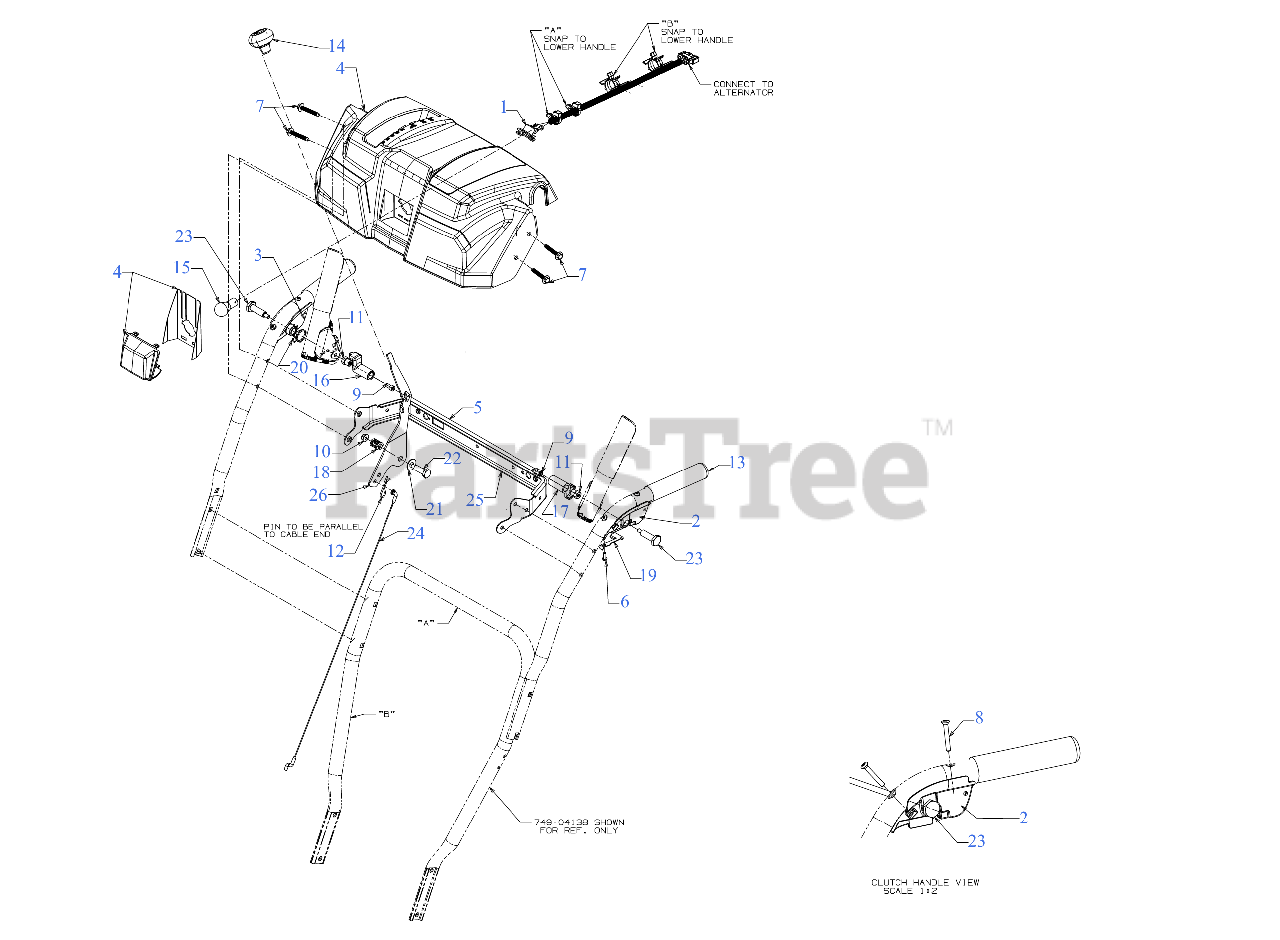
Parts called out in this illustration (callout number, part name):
1	LIGHT HARNESS
2	CLUTCH LOCK HANDLE ASSEMBLY (LH)
3	CLUTCH LOCK HANDLE ASSEMBLY (RH)
4	HANDLE PANEL(W/LIGHT)
6	SCREW #8-16 x .50
7	SCREW 1/4-20 x 1.625
8	SCREW #10-24 x 1.375
9	SCREW 1/4-20 x .50
10	FLANGE LOCK NUT
11	HEX NUT W/PATCH
12	INTERNAL COTTER PIN
14	SHIFT KNOB
15	LAMP-12 VOLT
17	CLUTCH LOCK CAM
18	COMPRESSION SPRING
19	CLUTCH SPRING
20	TORSION SPRING
21	FLAT WASHER .40X.88X.060
22	SHOULDER SCREW
23	SHOULDER SCREW .437 x 1.345 1/4-20
24	SPEED SELECTOR CABLE (PLASTIC)
25	HANDLE SUPPORT BRACKET (POWDER BLACK)
